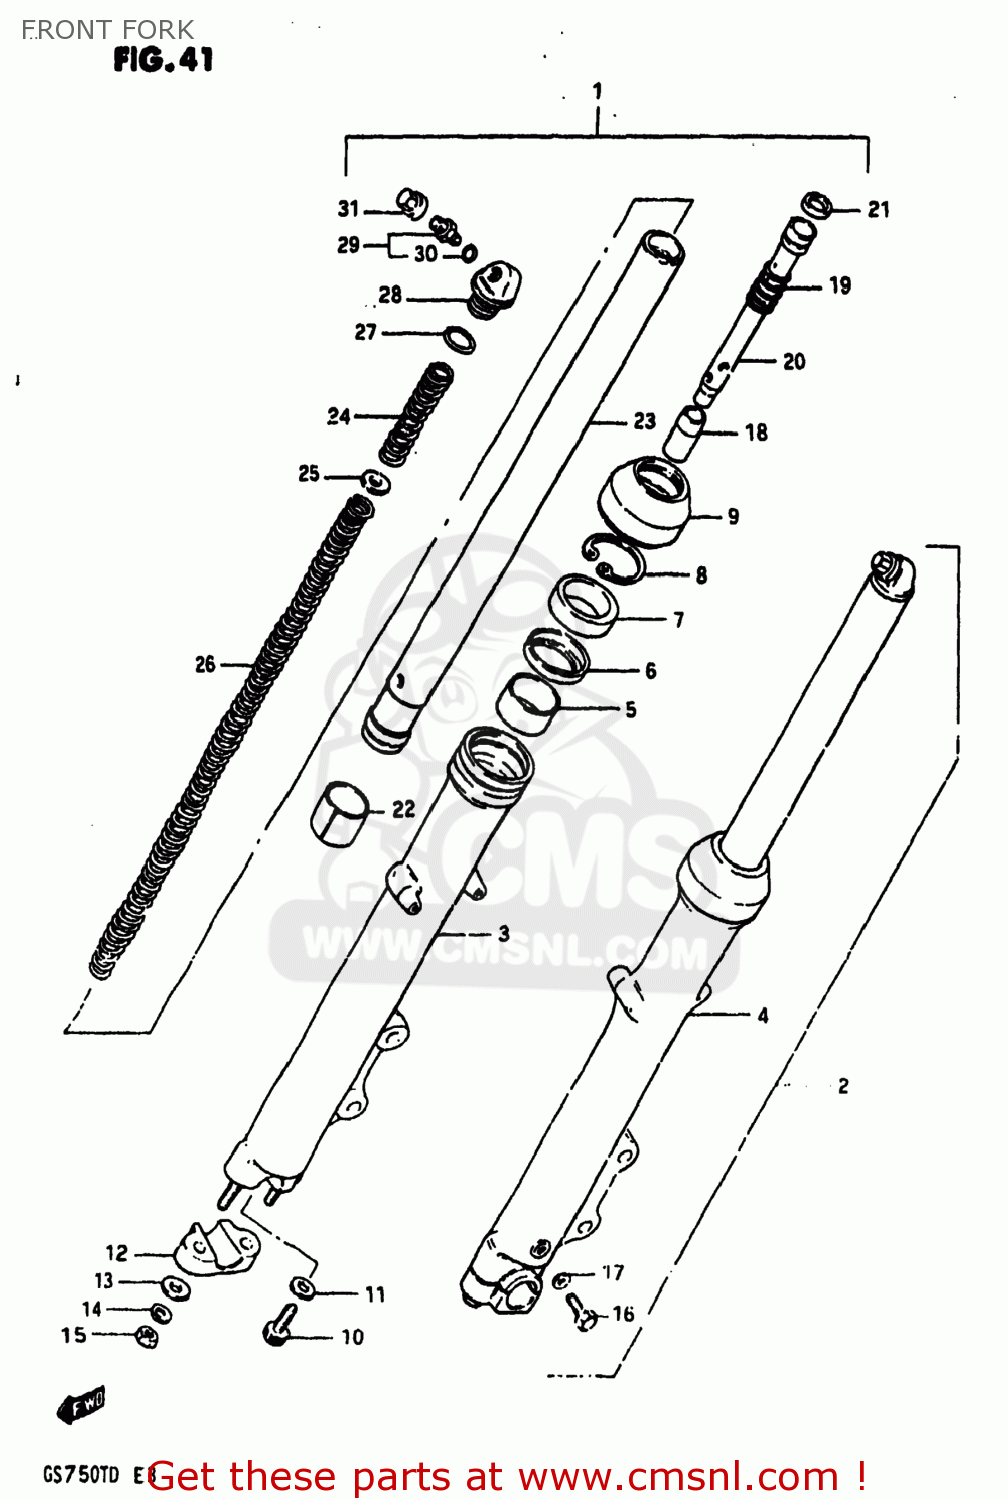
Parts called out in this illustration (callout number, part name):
1	DAMPER ASSEMBLY,RIGHT
2	DAMPER ASSEMBLY,LEFT
3	TUBE,FORK,OUTER,RIGHT
4	TUBE,FORK,LEFT,OUTER
5	BUSH,GUIDE
6	SPACER,SEAL
7	OIL SEAL,FRONT FORK
8	CIRCLIP,FORK OIL SEAL
9	BOOT
10	BOLT(8X27)
11	GASKET (NAS)
12	HOLDER,AXLE
13	WASHER
14	LOCK WASHER
15	NUT (8MM)
16	BOLT
17	GASKET,DRAIN,PLUG (NAS)
18	PIECE,OIL LOCK
19	SPRING,FORK REBOUND
20	CYLINDER,FRONT FORK
21	RING
22	PISTON
23	TUBE,FORK,INNER
24	SPRING
25	WASHER,SPRING
26	SPRING,FRONT FORK
27	O-RING
28	BOLT,FORK INNER TUBE
29	VALVE,AIR
30	O-RING
31	CAP
